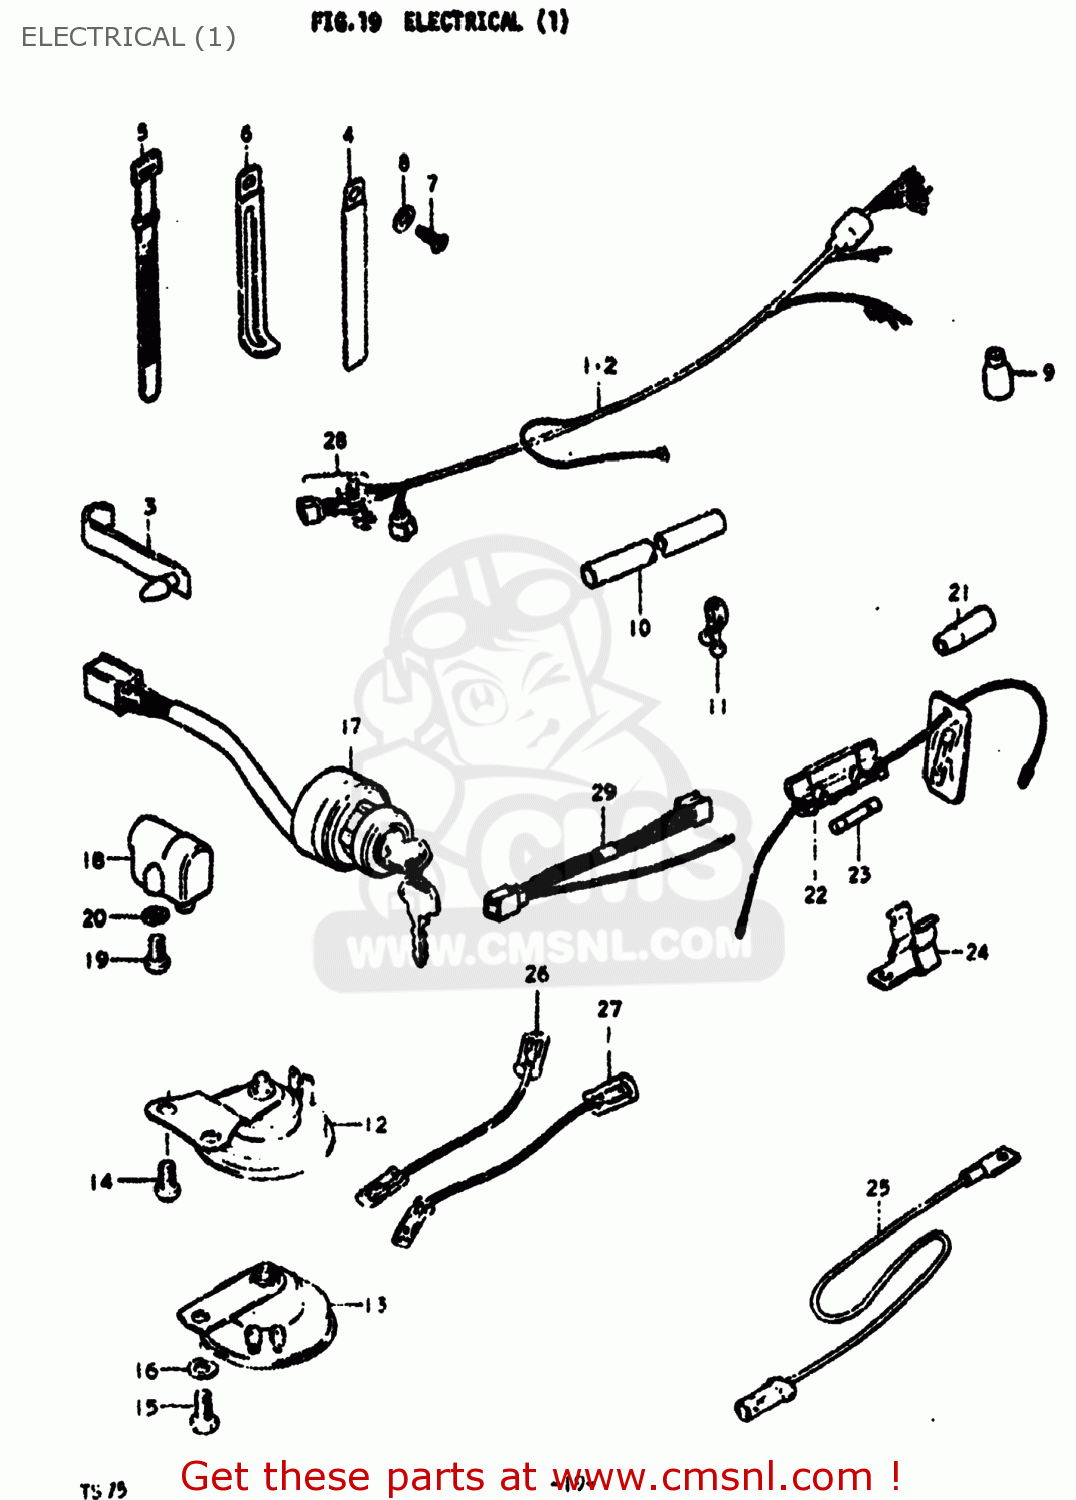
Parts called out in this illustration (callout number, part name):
1	HARNESS,WIRING
2	HARNESS,WIRING
3	BAND
4	CLAMP
5	CLAMP
6	CLAMP
8	WASHER
9	BOOT,WIRING HARNESS
11	CLIP(ID:11.5)
12	HORN ASSEMBLY
13	HORN ASSEMBLY
14	SCREW
15	BOLT
16	LOCK WASHER
17	SWITCH ASSEMBLY,IGNITION
18	LOCK ASSY,STEERING
19	Screw
20	LOCK WASHER
21	SEAL,DUST(10X17X45)
22	BOX ASSEMBLY,FUSE
23	FUSE(15A)
24	HOLDER,FUSE CASE
25	WIRE,WIRING HARNESS LEAD
26	LEAD WIRE
27	WIRE
28	WIRE
